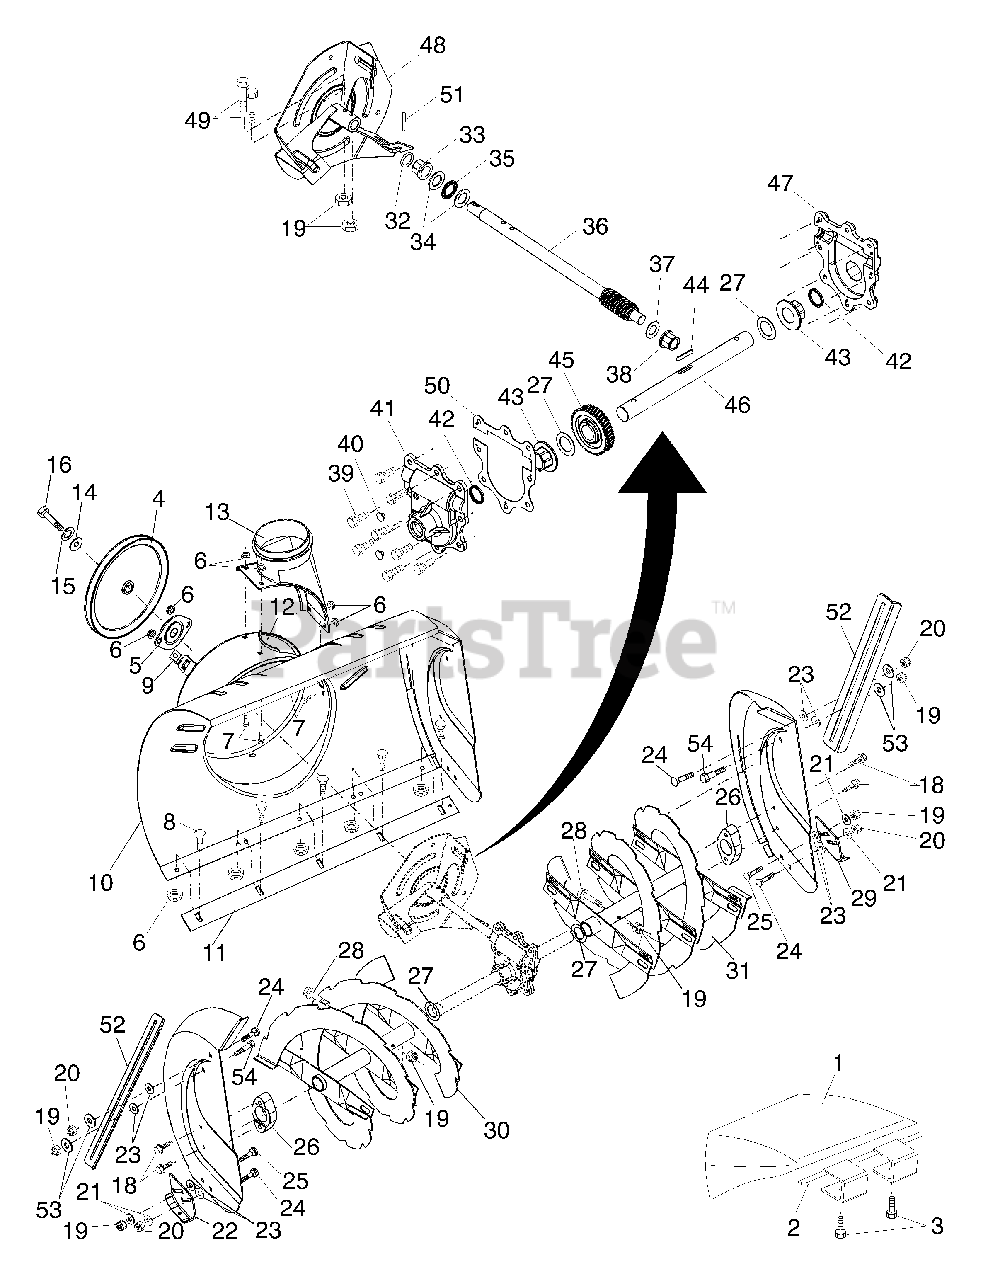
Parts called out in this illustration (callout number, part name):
1	Bag, Weight
2	Bracket, Weight Bag
3	Screw, Hex Head 5/16-18 x 1-1/2
4	Pulley, Impeller
5	Bearing Assembly, Flange
6	Nut, Hex Flange 5/16-18
7	Bolt, Flat Head, Carriage 5/16-18 x 5/8
8	Bolt, Carriage 5/16-1 8 x 5/8
9	Nut, Cage 3/8-16
10	Housing, Auger
11	Bar, Scraper
12	Bracket, Corner Discharge
13	Base, Discharge Chute
14	Washer, Flat
15	Washer, Lock 5/16
16	Screw, Hex Head 5/16-18 x 3/4
18	Screw, Hex Head 5/16 x 1
19	Nut, Hex Lock 1/4-20
20	Nut, Hex Lock 5/16-18
21	Washer, Flat
22	Skid Plate, RH
23	Washer, Nylon, Friction
24	Bolt, Carriage 5/16-18 x 3/4
25	Bolt, Shoulder
26	Bearing, Auger
27	Washer, Thrust, 1"
28	Bolt, Shoulder 1/4-20 x 2
29	Skid Plate, LH
30	Auger Assembly, RH
31	Auger Assembly, LH
33	Bushing, Flange 3/4
34	Washer, Thrust 3/4
35	Bearing, Thrust 3/4
36	Shaft, Impeller
37	Washer, Thrust 5/8
38	Bushing, Flange 5/8
39	Screw, Hex Head 5/16-18 x 3/4
40	Plug, Case
41	Housing, Gearbox, RH
43	Bushing, Flange, 1"
44	Key, Square 1/4 x 1/4 x 7/8
45	Gear, Worm
46	Shaft, Auger
47	Housing, Gearbox, LH
48	Impeller Assembly
49	Screw, Hex Head 1/4-20 x 1-5/8
50	Gasket, Gearbox
51	Pin, Roll 3/16 x 1-1/8
52	Bar, Drift Cutter
53	Washer, Flat
54	Bolt, Shoulder
